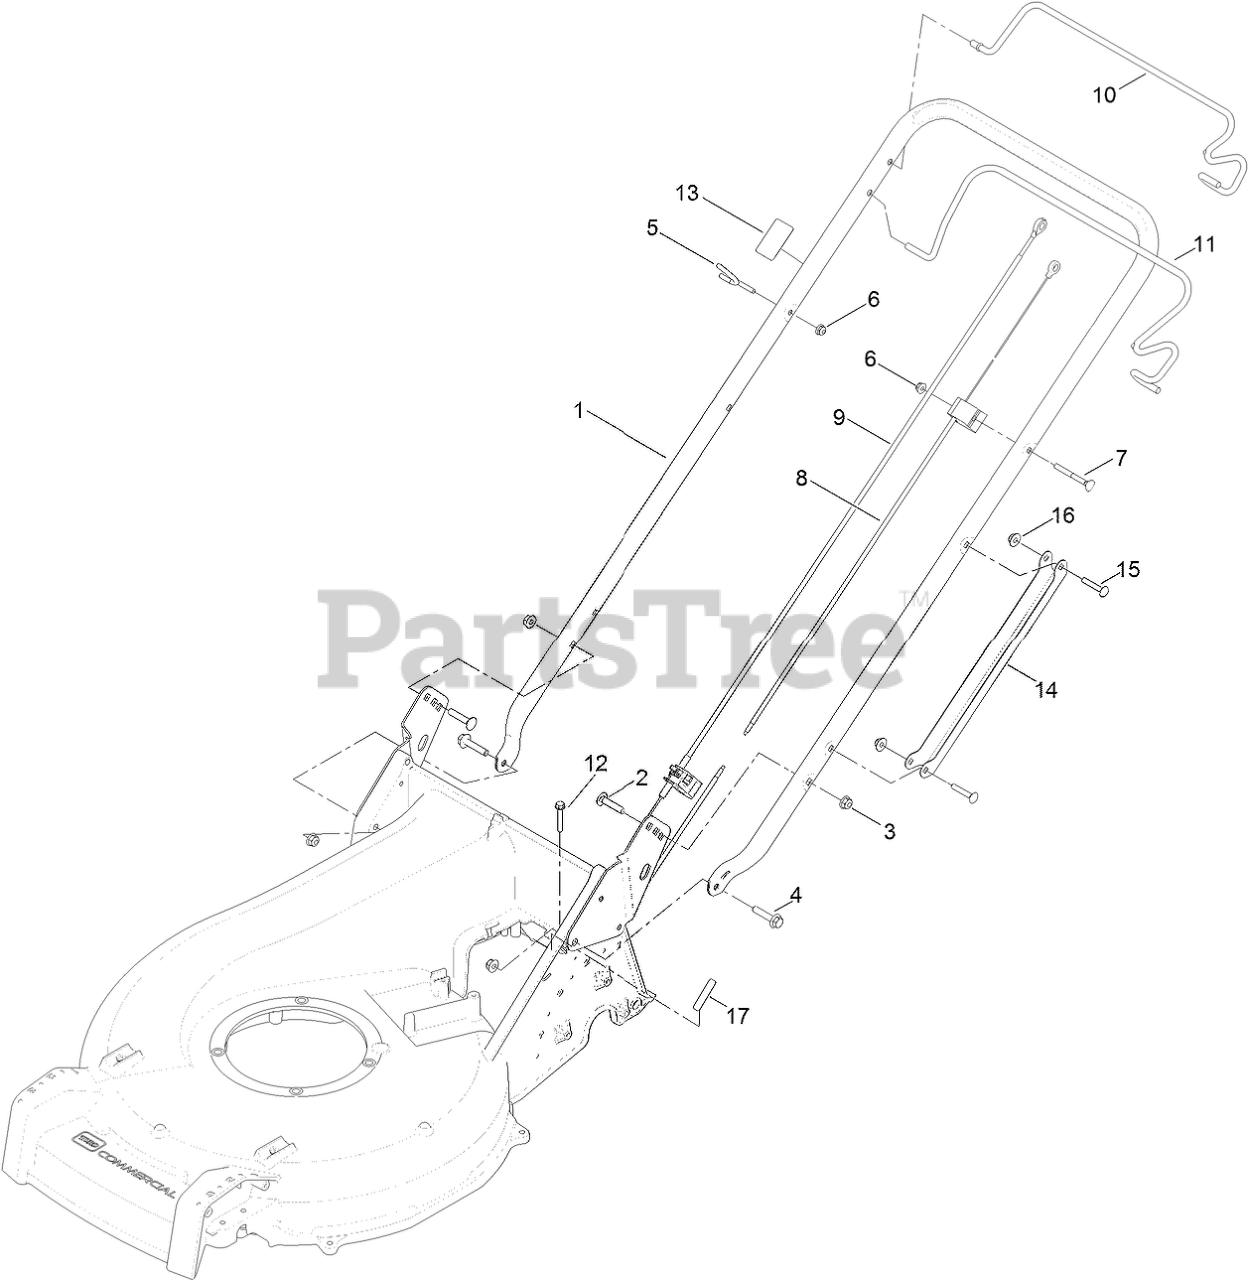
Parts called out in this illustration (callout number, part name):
1	HANDLE
2	BOLT-CARR
3	NUT-HF, NI
4	SCREW-HHF
5	GUIDE-ROPE
6	NUT-HF
7	SCREW-HANDLE
8	CABLE-BRAKE
9	CABLE-TRACTION
10	BAIL-TRACTION
11	BAIL-BRAKE
12	SCREW-HWH
13	DECAL-PRIMER
14	GUARD-CABLE, HANDLE
15	SCREW-CARR
16	NUT-HEX FLG
